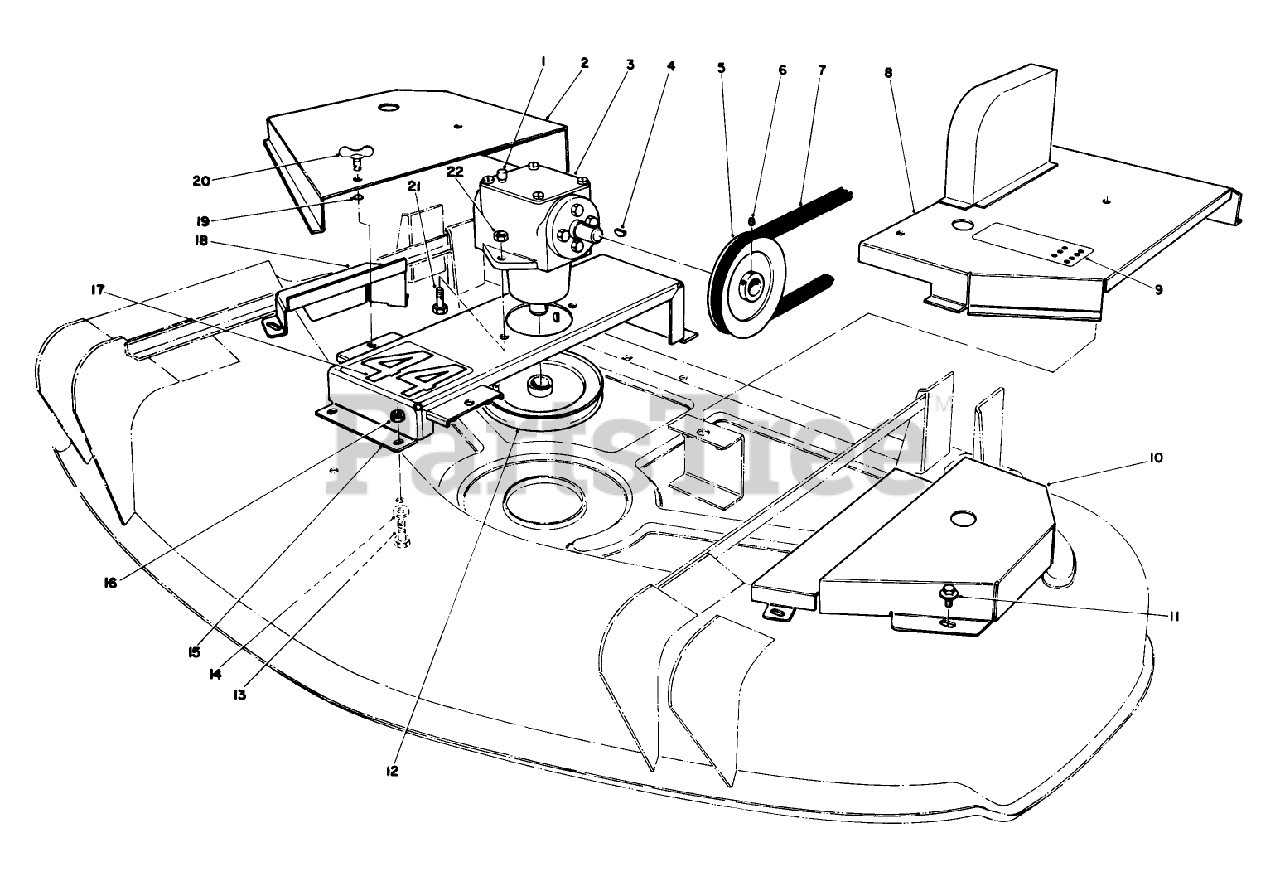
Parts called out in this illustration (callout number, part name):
4	KEY-WOODRUFF
6	SCREW-SET, SQH
7	V-BELT-DRIVE, DECK
11	SCREW-HHFTF
13	SCREW-HH
14	WASHER-PLAIN
16	NUT-LOCK, CONE
17	DECAL-44 INCH
19	RING-RETAINING
20	STUD-HEAD, WING
21	SCREW-HH
22	NUT-LOCK, CONE
